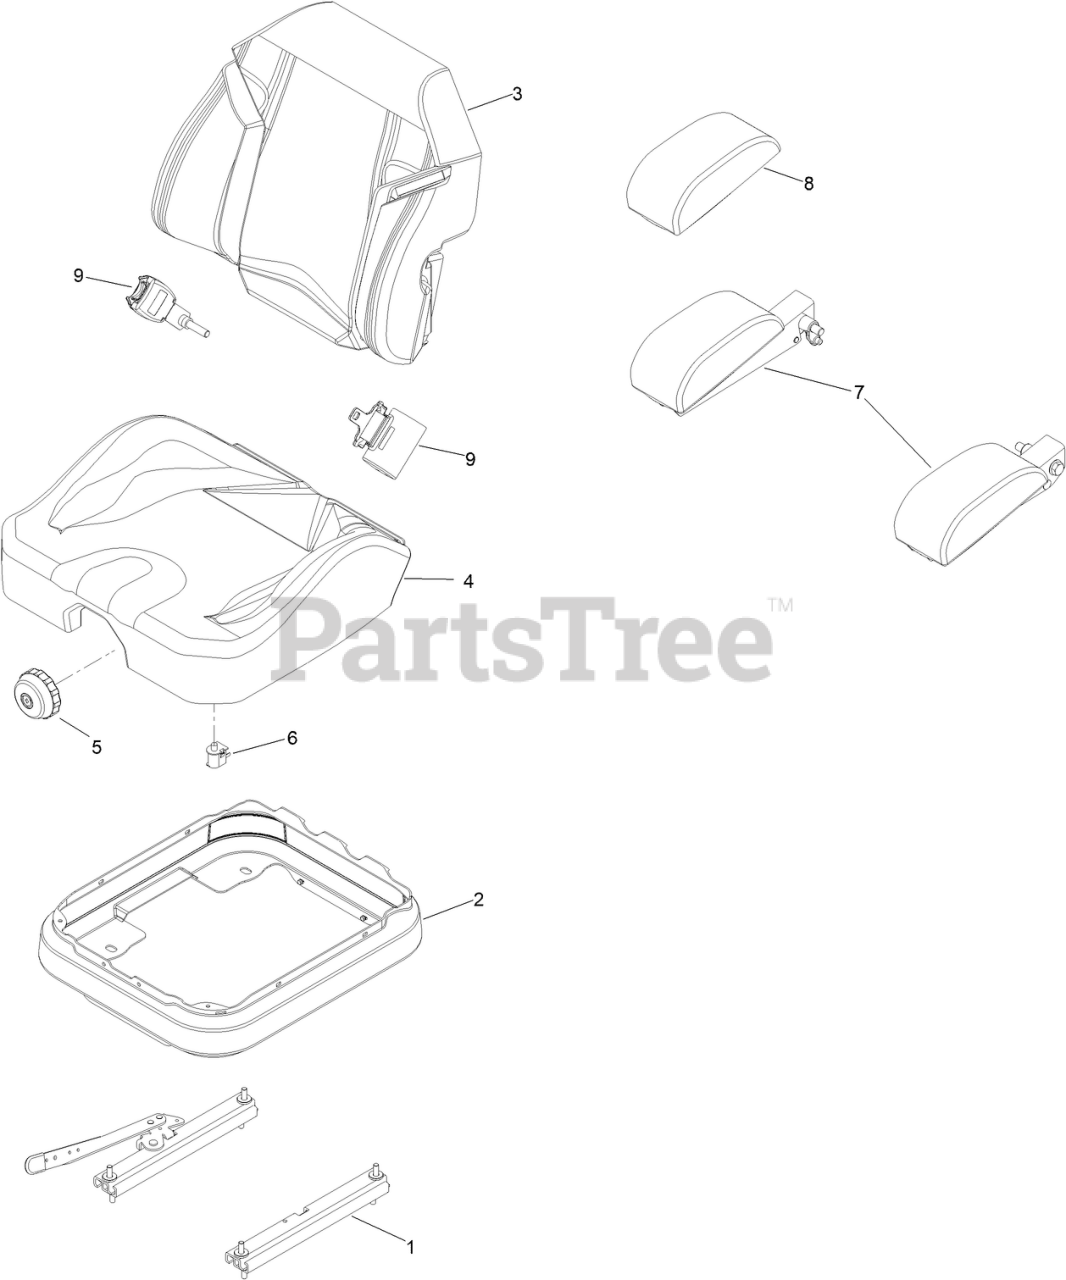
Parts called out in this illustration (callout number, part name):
1	SET, SEAT TRACK
2	COVER-SUSPENSION, BELLOWS
3	COVER-BACK
4	COVER-CUSHION
5	KNOB-ADJUSTER
6	SWITCH-BAIL
7	ARMREST KIT
8	ARM REST PAD SET
9	SEAT BELT SERVICE KIT
